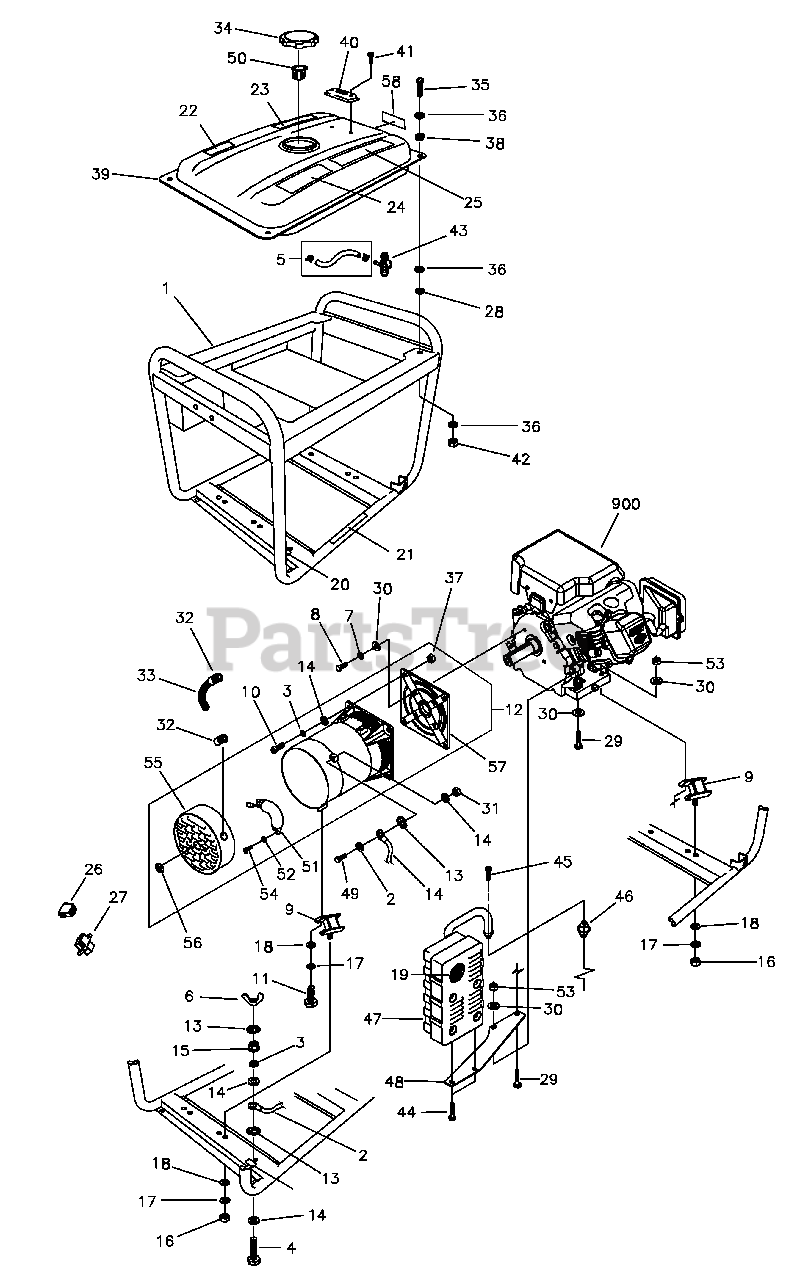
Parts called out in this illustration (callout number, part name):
1	Cradle
3	Washer, Lock, M8 Zinc Plated
4	Hex Bolt, M8 x 30, Zinc Plated
5	Kit, Fuel Line
7	Washer, Lock M8
8	HHCS, 5/16 - 24
9	Absorber, Vibration
10	SHCS, M8 x 30
11	HHCS
13	Washer, M8, Zinc Plated
14	Washer, Flat, M8 x 16
15	Hex Nut, M8, Zinc Plated
16	Nut, M10
17	Washer, Lock, M10 Blk Zinc Plated
18	Washer, Flat, M10
19	Screen, Spark Arrest
21	Decal, Warning, Exhaust
22	Decal, Warning CO
23	Decal, Warning Fuel
24	Decal, Warning Fuel Fill
25	Decal, Fuel Instructions
27	Wire End Seat, White
29	HHCS, M8 x 35
30	Washer, Flat, M8 x 16
31	Nut, Nylon M8, Zinc Plated
32	Quick Connector
35	Screw, M6 x 30
36	Washer, Flat, M6 x 24
37	Nut, M8
39	Assy, Tank, Fuel
41	Screw, M5 x 10
42	Nut, Nylon, M6
43	Valve, Fuel
44	HHCS, M6 1.0 x 12 with LW
45	SHCS, M6 - 1 x 20
46	Gasket, Exhaust
48	Bracket, Muffler
49	Screw, M8 x 25
52	Washer, Capacitor
53	Nut, Nylon, M8
54	Screw, Capacitor
58	Decal, Fuel Shut Off
900	Engine
